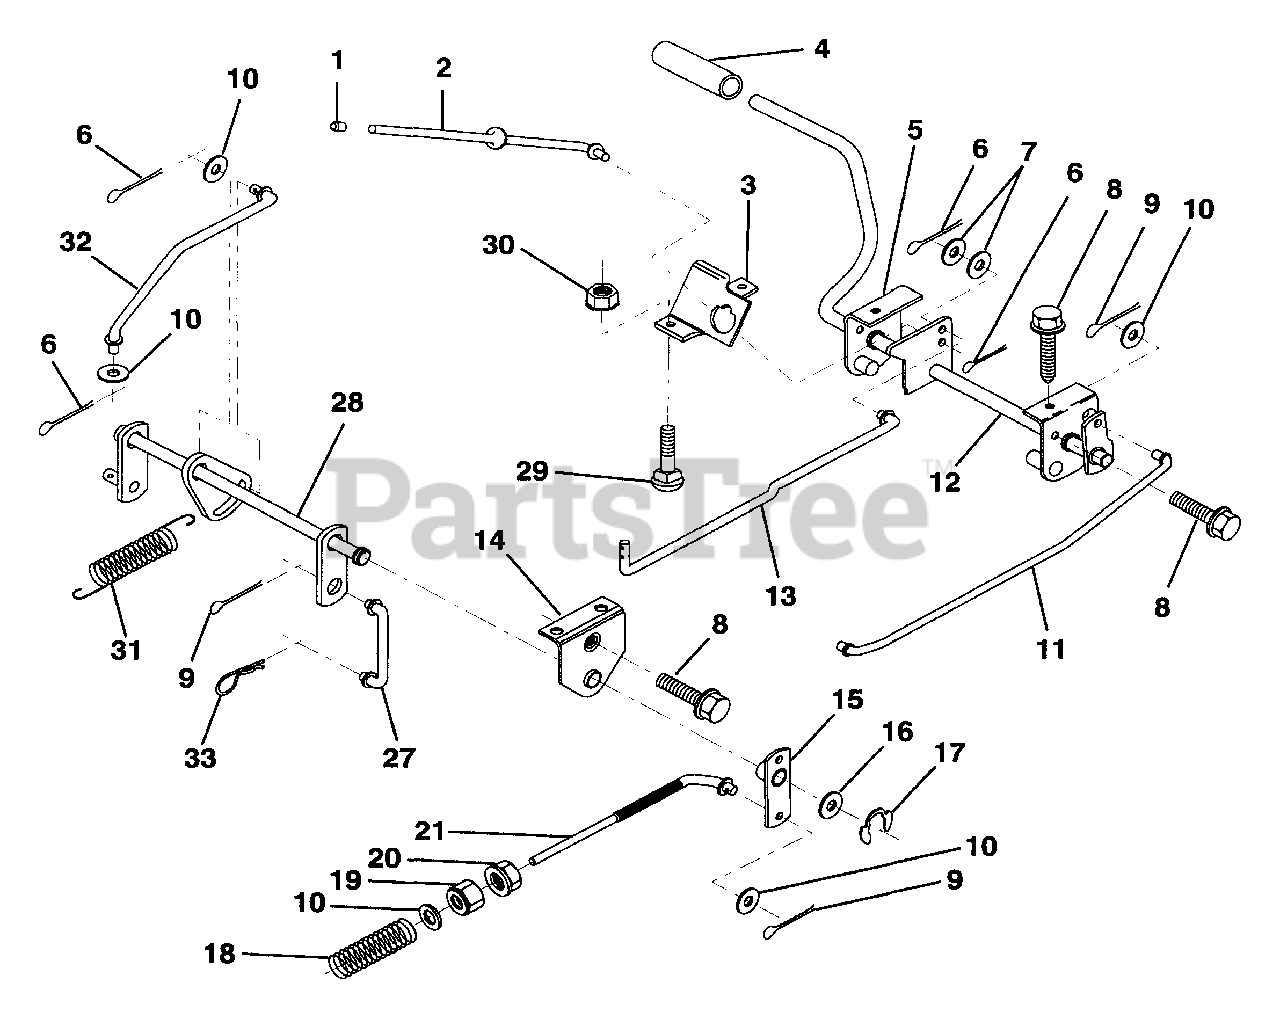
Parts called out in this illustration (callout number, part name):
1	Cap, Plunger
2	Rod, Parking Brake
3	Bracket, Parking Brake
4	Cover, Pedal
5	Bracket, Clutch/Brake Pedal, L.H.
6	Pin, Cotter 3/32 x 3/4
7	Washer 13/32 x 5/8 x 16 Gauge
8	Screw, Hex Head, Thd., Roll. 5/16-18 x 1/2
9	Pin, Cotter 1/8 x 3/4
10	Washer 13/32 x 13/16 x 16 Gauge
11	Rod, Brake, Front
12	Assembly, Clutch/Brake Pedal
13	Rod, Clutch
14	Bracket, Lift Shaft
15	Assembly, Brake, Pivot, Arm
16	Washer 25/32 x 1-1/8 x 16 Gauge
17	Ring, Klip
18	Spring, Brake Rod
19	Nut, Hex, Jam 3/8-16 UNC
20	Nut, Crownlock 3/8-16 UNC
21	Rod, Brake, Rear
27	Link, Lift, Rear
28	Assembly, Rear Mower Lift
29	Bolt, Rd Hd Sqnk 5/16-18 UNC
30	Nut, Hex, Keps 5/16-16 UNC
31	Spring, Counterbalance
32	Link, Lift Lever
33	Retainer Spring
